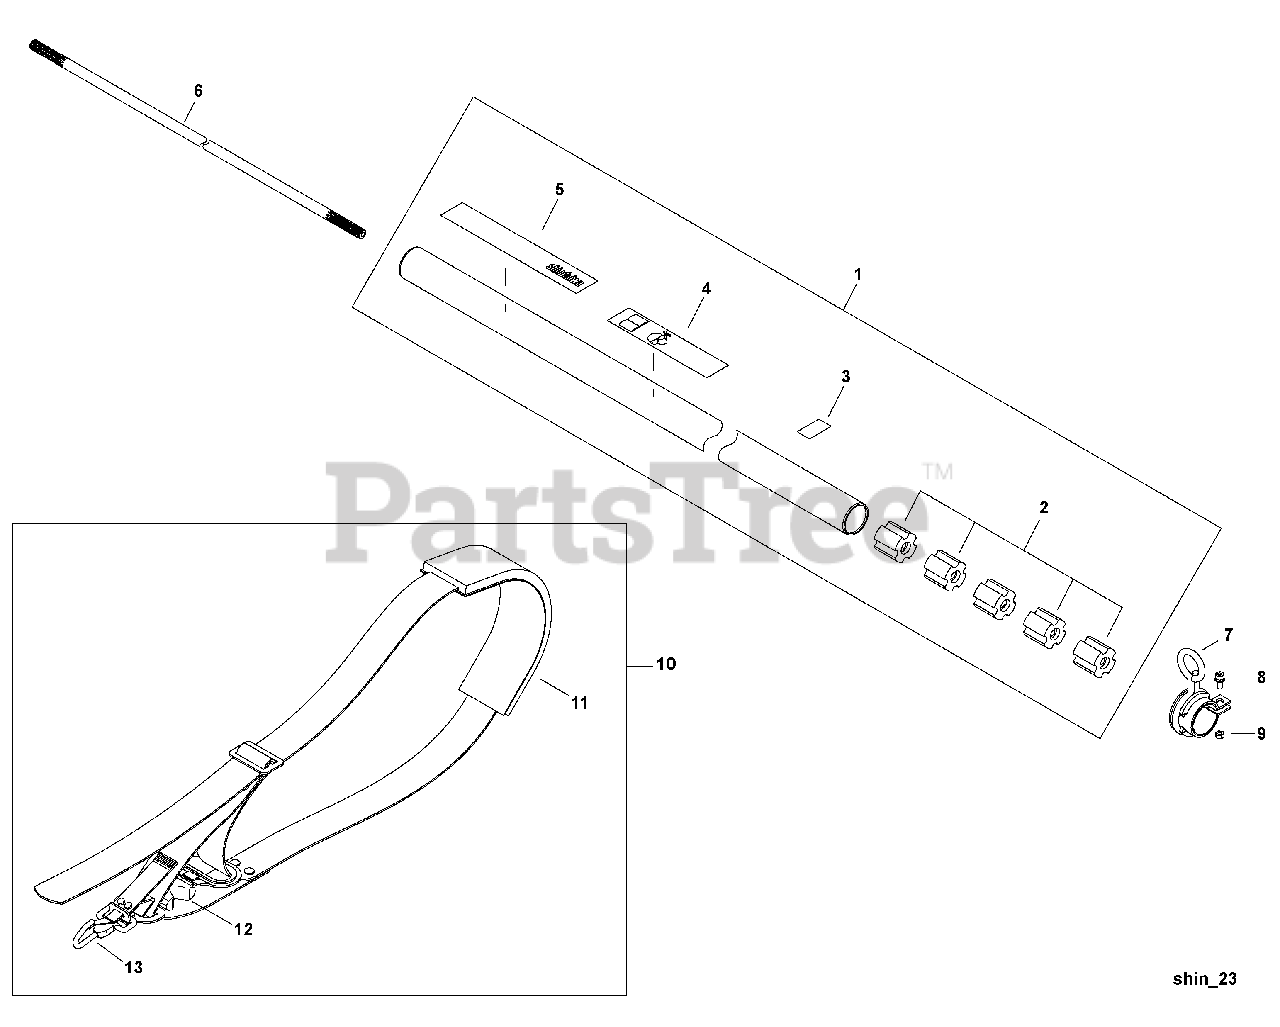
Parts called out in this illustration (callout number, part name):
1	MAIN PIPE ASSY
2	BUSHING
3	LABEL - INSTRUCTION
4	LABEL - CAUTION
5	LABEL - SHINDAIWA PROFESSIONAL
6	DRIVESHAFT
7	HANGER
8	SCREW - 5X12
10	HARNESS ASSY
11	PAD
12	CUSHION, HARNESS
13	HOOK
